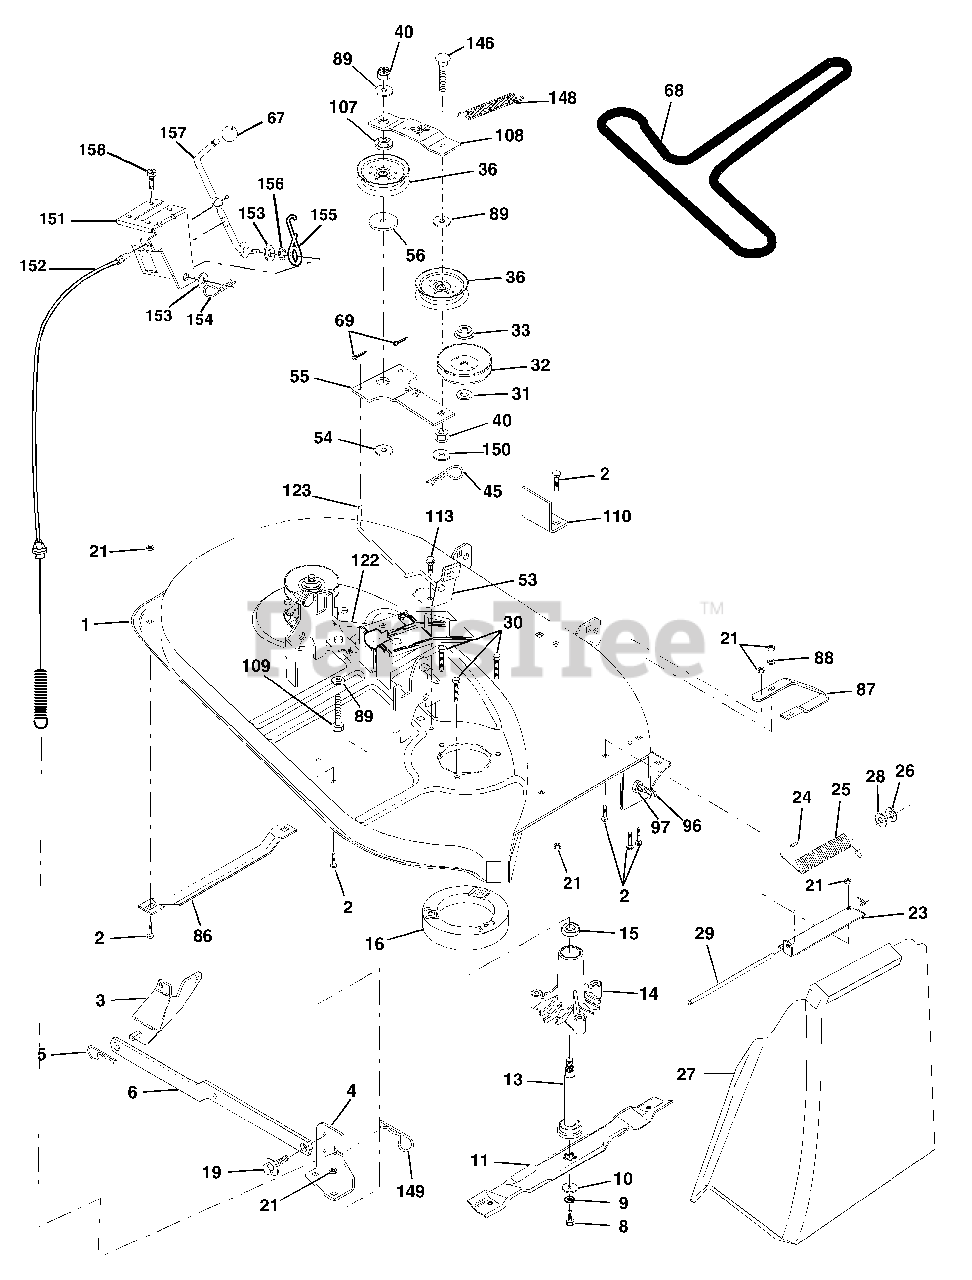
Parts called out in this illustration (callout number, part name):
1	Mower Housing Assembly
2	Bolt, Carriage 5/16-18 x 3/4
3	Bracket Asm. Fram Sway Bar
4	Bracket, Asm. Deck Sway Bar
5	Retainer, Spring
6	Bar Sway Deck
8	Bolt, Hex 3/8-24 x 1-1/4 Gr 8
9	Washer, Lock, Hlcl Sprg 3/8
10	Washer, Hard Blade Mower Vented
11	Blade, Mower, Mulching 38"
13	Shaft and Bearing Assembly
14	Mandrel Housing, Vented
15	Ball Bearing, Mandrel
16	Stripper, Mower, Vented
19	Bolt, Shoulder
21	Nut, Crownlock 5/16-18
23	Bracket, Mower Deflector
24	Cap, Sleeve
25	Spring, Deflector
26	Nut, Push
27	Shield, Deflector
28	Washer 11/32 x 3/4 x 16 Ga
29	Rod, Hinge
30	Screw, Thdro
31	Washer, Spacer
32	Pulley, Mandrel
33	Nut, Flangelock 9/16
36	Pulley, Idler, Flat
40	Nut Crownlock 3/8-16
45	Retainer, Spring
53	Brake Assembly
54	Washer Hardened
55	Idler Arm Assembly
56	Spacer, Retainer
67	Knob
68	Belt
69	Pin, Cotter 3/32 x 3/4
86	Runner, LH
87	Runner, RH
88	Washer 11/32 x 3/4 x 16 Ga
89	Washer 13/32 x 1 x 12 Ga
96	Bolt 3/8-16 x 1-1/4
97	Nut Centerlock 3/8-16
107	Spacer, Retainer
108	Stiffener, Idler Arm
109	Bolt, Hex Head 3/8-16 x2-1/2
110	Upstop Deck Front 38"
113	Screw 5/16-18 x 3/4
122	Rod, Brake, LH
123	Rod, Brake, RH
146	Bolt Carriage Idler
148	Spring Return Idler
149	Retainer Spring Yellow Zinc
150	Washer 9/32 x 3/4 x 16 Ga.
151	Bracket Clutch
152	Cable Clutch 38 In
153	Washer Flat 3/8" Type B
154	Spring Retainer
155	Spring Retention Lever
156	Spacer
157	Rod Clutch
158	Screw Hex Thd Cut 1/4-20 x 1/2
